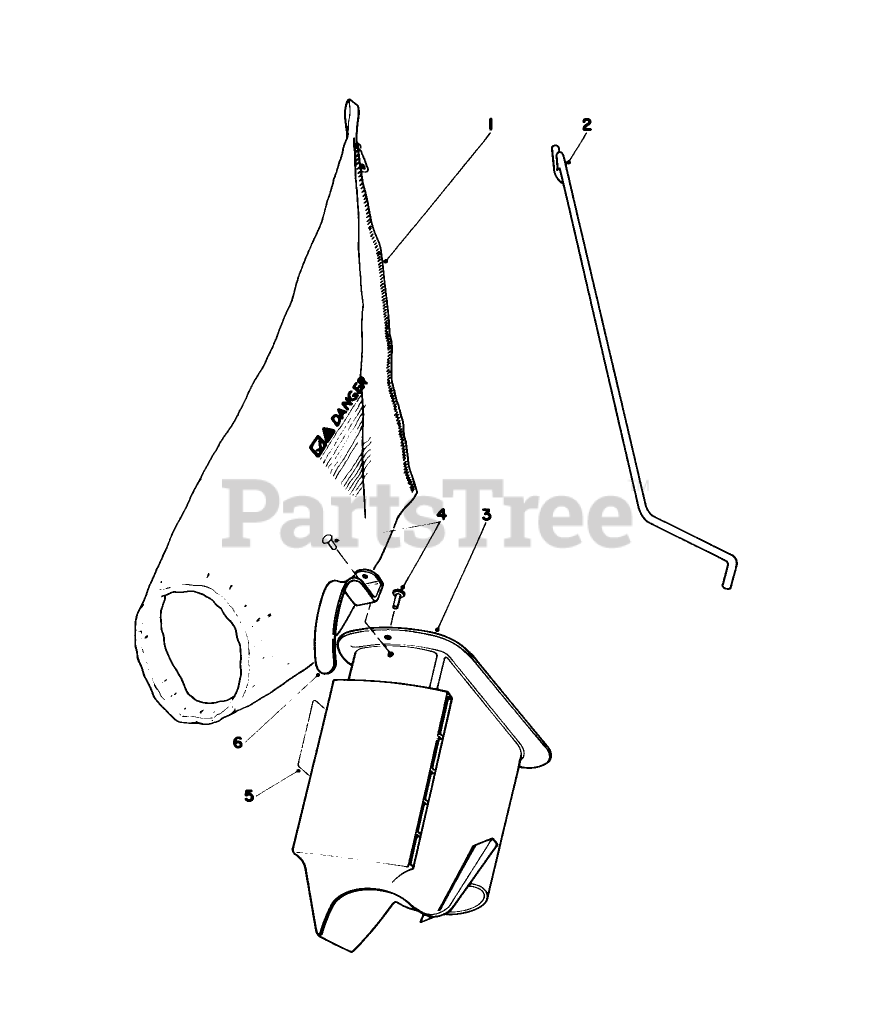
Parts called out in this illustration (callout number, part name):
2	BAG ROD
3	Grass Chute (Incl. Ref. #46)
4	RIVET 3/16 X 7/16
5	BAG CHUTE DECAL
